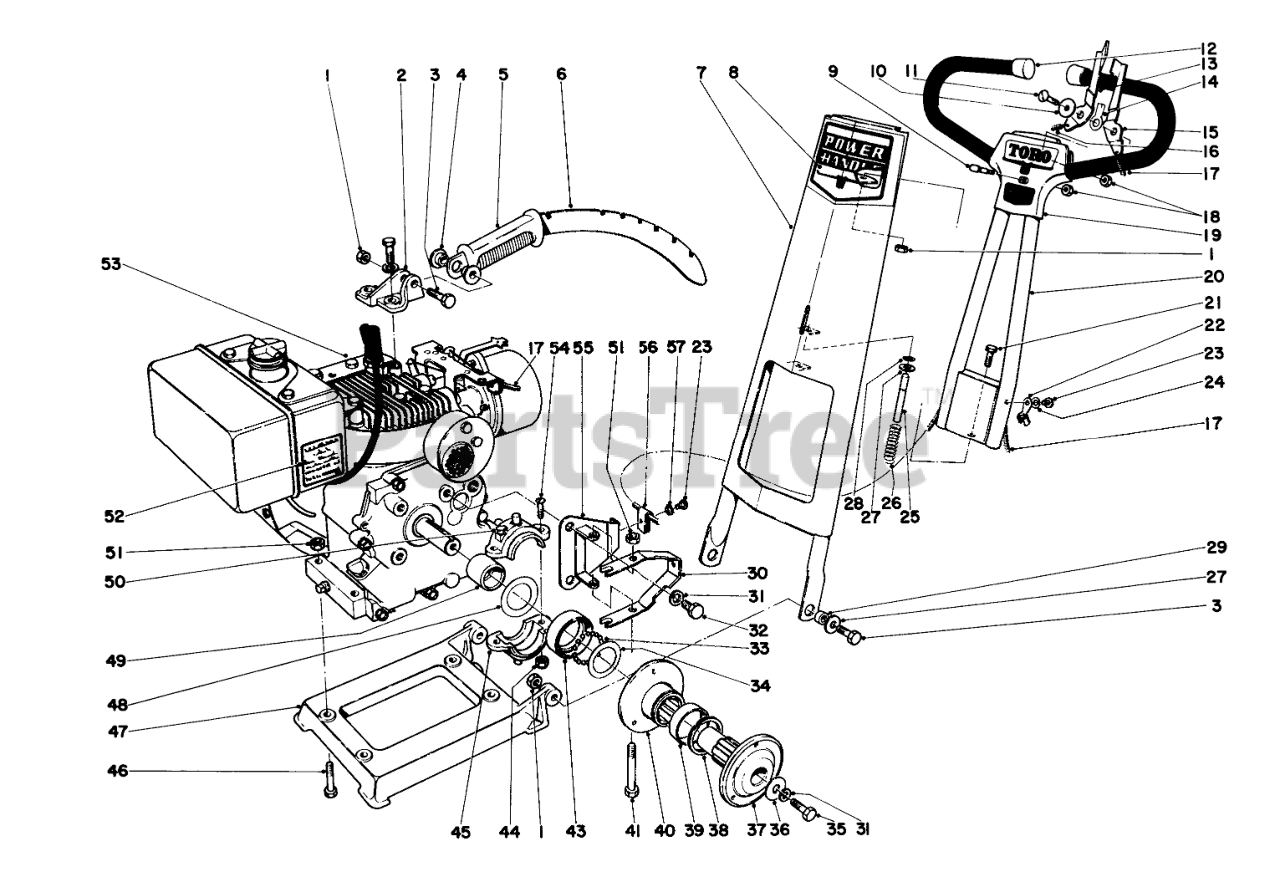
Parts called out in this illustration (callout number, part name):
1	Nut
2	Handle Adjustment Bracket
3	SCREW-HH
4	GROMMET
5	Grip Handle
6	Bar Adjustment
7	Lower Handle Assembly (Incl. Ref. Nos. 8 & 25 thru 28)
8	Decal
9	Screw
10	WASHER CONTROL PIVOT
12	Button Plug
13	Clutch Lever
14	Washer
15	Throttle Lever
16	CLUTCH CONTROL ASM
17	Throttle Control Assy.
18	NUT-LOCK, NI
19	Escutcheon Plate
20	Upper Handle (Incl. Ref. #12)
21	SCREW-HH
22	Clamp
23	SCREW-PPH
24	WASHER-LOCK
26	SPRING
27	WASHER-PLAIN
28	RING-RETAINING, EXT
29	Grommet
30	Shift Fork
31	WASHER-LOCK
32	SCREW-HH
33	Ball
34	Check Washer
35	SCREW-HH
36	Washer
37	Body, Clutch
38	1-1/2X048 EX MED RING
39	IDLER BUSHING
40	Sliding Flange
41	SCREW-HH
43	Ball Race
44	NUT-LOCK
45	Slip Ring Kit (Inc. Ref. #50)
46	SCREW-HH
47	Engine Base
48	Washer-Thrust
49	Inner Ball Race
50	OILER
51	NUT-LOCK NI
52	Decal
53	Engine
54	SCREW
55	Bracket Mount
56	3/16 SUPPORT
57	WASHER-LOCK, EXT
